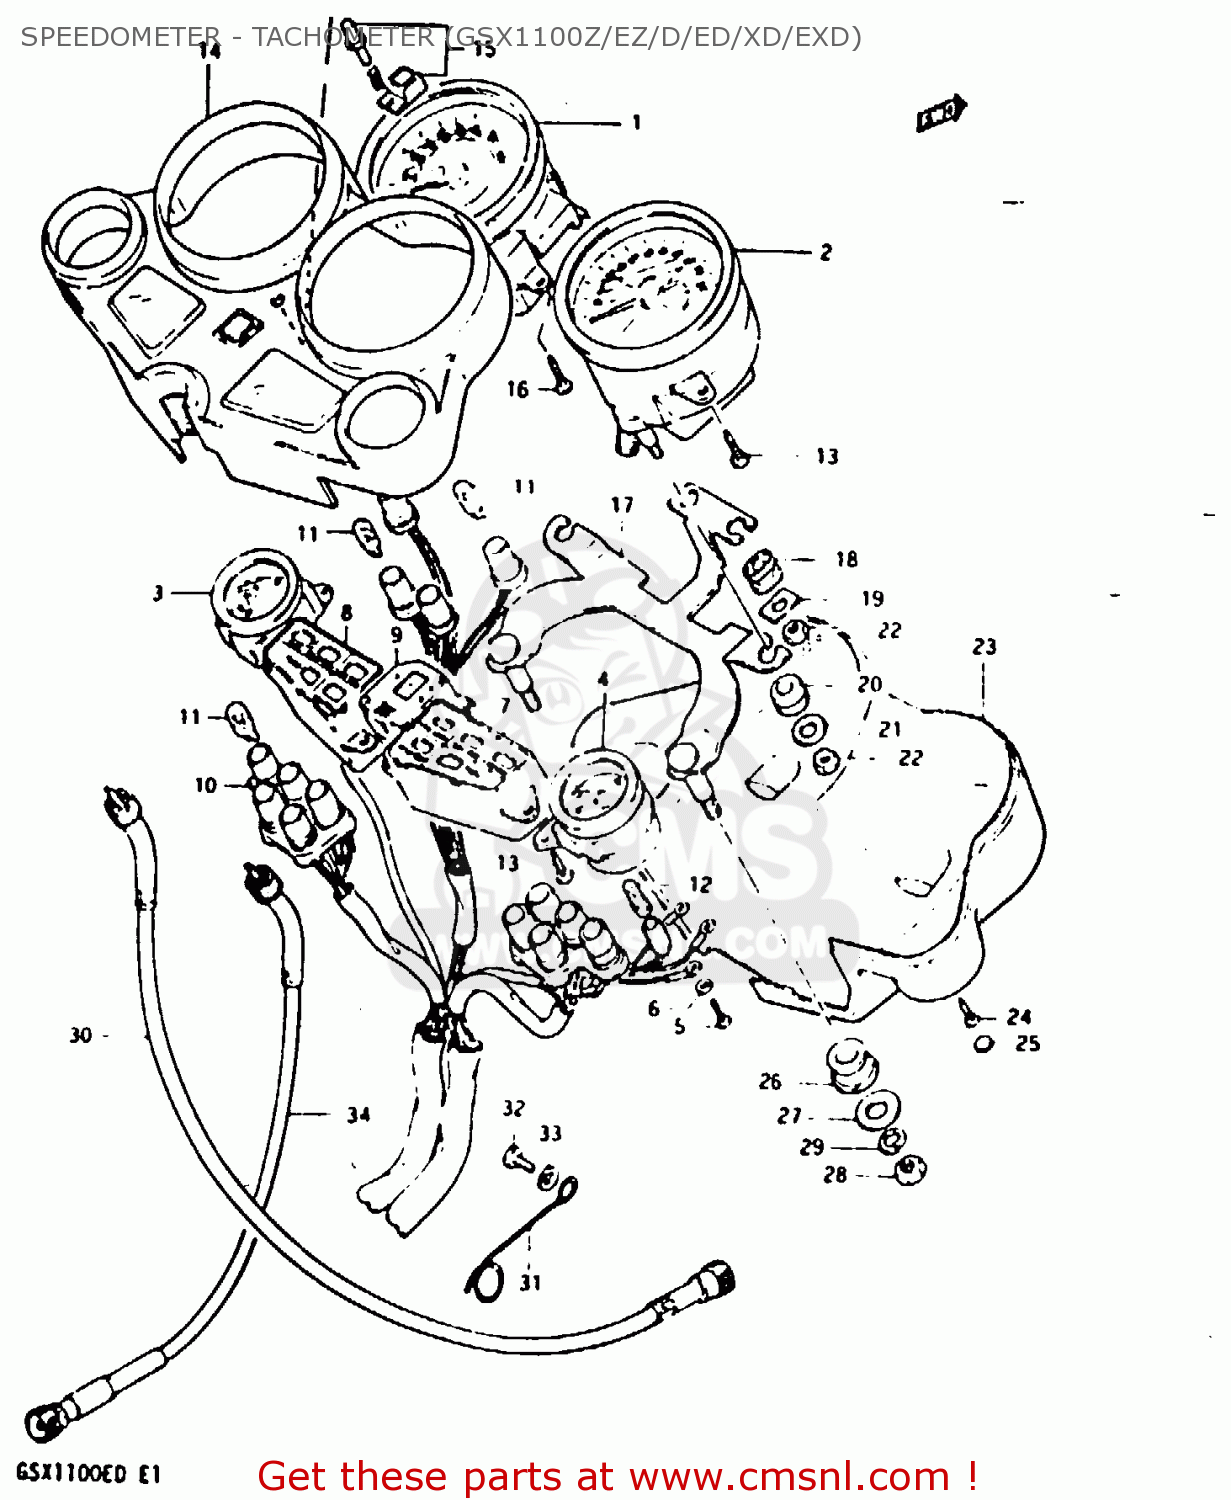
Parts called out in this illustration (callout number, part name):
1	SPEEDOMETER (MILE/KILO)
2	METER,TACHOMETER
3	METER,FUEL
4	METER,OIL TEMPERATURE
5	SCREW
6	WASHER
7	CASE,PILOT LAMP
8	CASE,PILOT LAMP
9	INDICATOR ASSEMBLY,GEAR POSITION
10	SOCKET,COMBINATION METER
11	BULB(12V3.4W,T10,BF175-01450A)
12	BULB(12V2W,STANLEY,A1272J)
13	SCREW
14	HOOD,METER
15	KNOB,TRIP METER
16	SCREW
17	BRACKET,COMBINATION METER
18	CUSHION,METER
19	WASHER,METER
20	CUSHION,METER
21	WASHER,METER
22	NUT
23	COVER,METER,UNDER
24	SCREW
25	CAP,METER LOWER CASE
26	CUSHION,METER BRACKET
27	WASHER (8.5X29X1.6)
28	NUT
29	LOCK WASHER
30	CABLE ASSY,SPEEDOMETER
31	CLAMP,SPEEDOMETER CABLE
32	BOLT, UPPER
33	WASHER
34	CABLE ASSEMBLY,TACHOMETER
